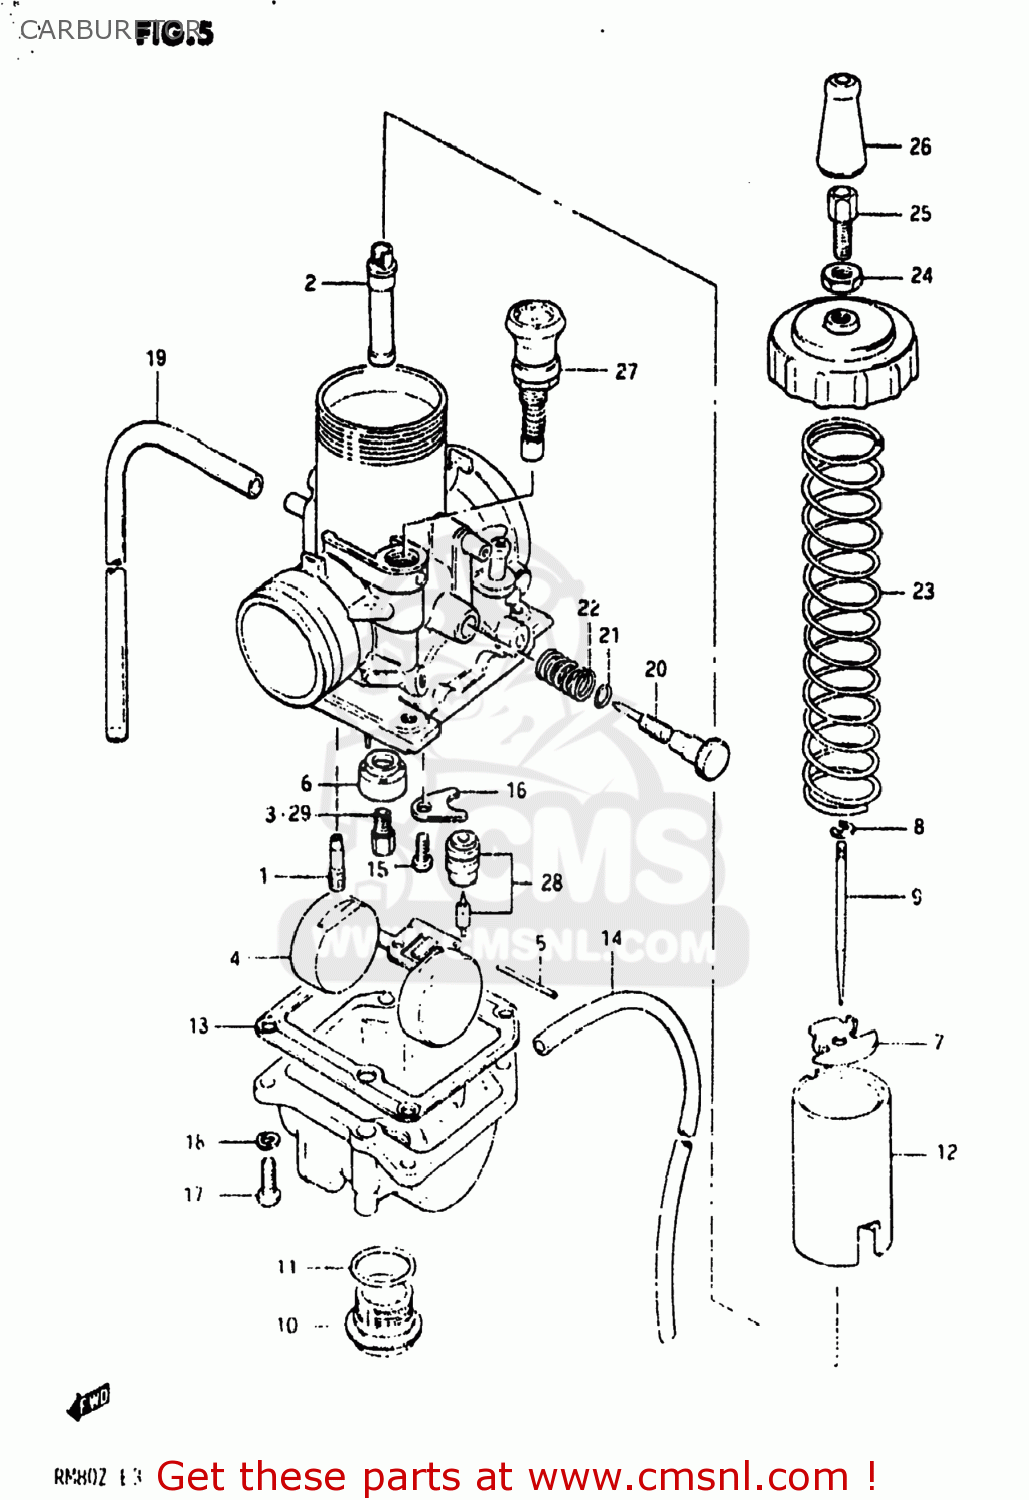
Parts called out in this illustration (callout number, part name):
1	JET,PILOT(45)
2	JET,NEEDLE
3	JET
4	FLOAT
5	PIN,FLOAT
6	RING
7	PLATE,THROTTLE VALVE
8	CLIP
9	NEEDLE,JET(5DP39-4)
10	PLUG
11	O RING
12	VALVE,THROTTLE
13	GASKET,FLOAT CHAMBER (NAS)
14	HOSE
15	SCREW
16	PLATE
17	SCREW
18	LOCK WASHER
19	HOSE
20	ADJUSTER
21	O RING
22	SPRING
23	SPRING,THROTTLE VALVE
24	NUT
25	ADJUSTER,CABLE
26	CAP,RUBBER
27	VALVE ASSEMBLY,STARTER
28	VALVE ASSEMBLY,NEEDLE
29	JET
